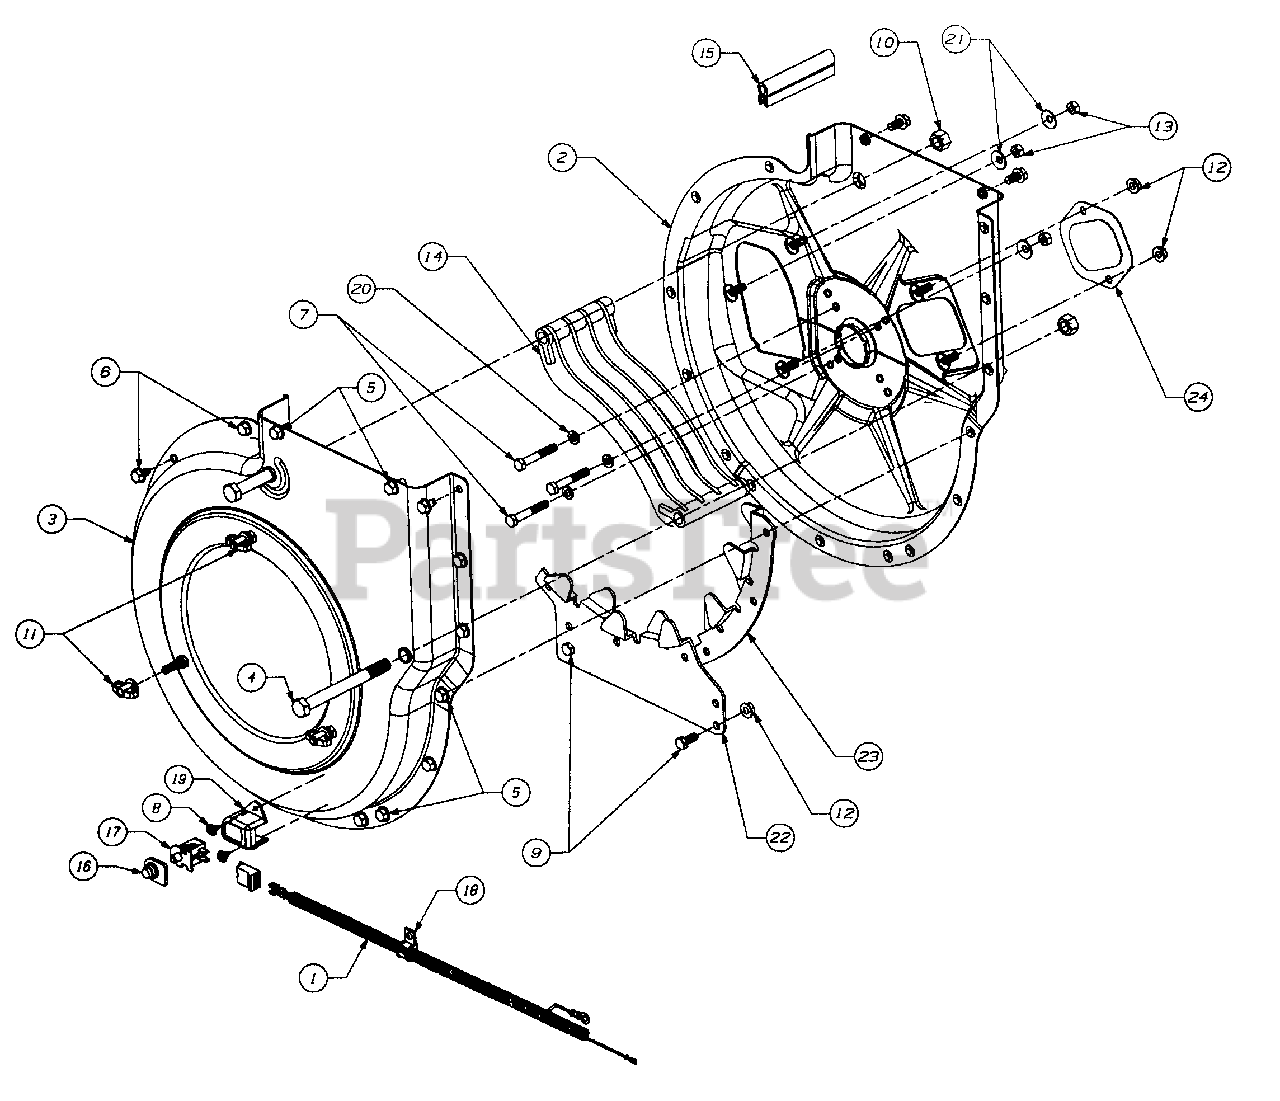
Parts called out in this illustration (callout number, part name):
1	HARNESS - CHIPPER-VAC
4	SCREW-HEX
5	SCREW-HEX SELF TAP
6	SCREW-HEX SELF TAP
7	SCREW-HEX
8	SCREW-HEX SELF TAP
9	SCREW-HEX
10	NUT-HEX LOCK
12	NUT-HEX LOCK
13	NUT-HEX (GR 5)
14	SCREEN
15	SEAL-RUBBER
16	COVER-SWITCH
17	SNAP MOUNT SWITCH
18	CLAMP
19	COVER-SWITCH
20	WASHER-LOCK
21	WASHER-BELL
